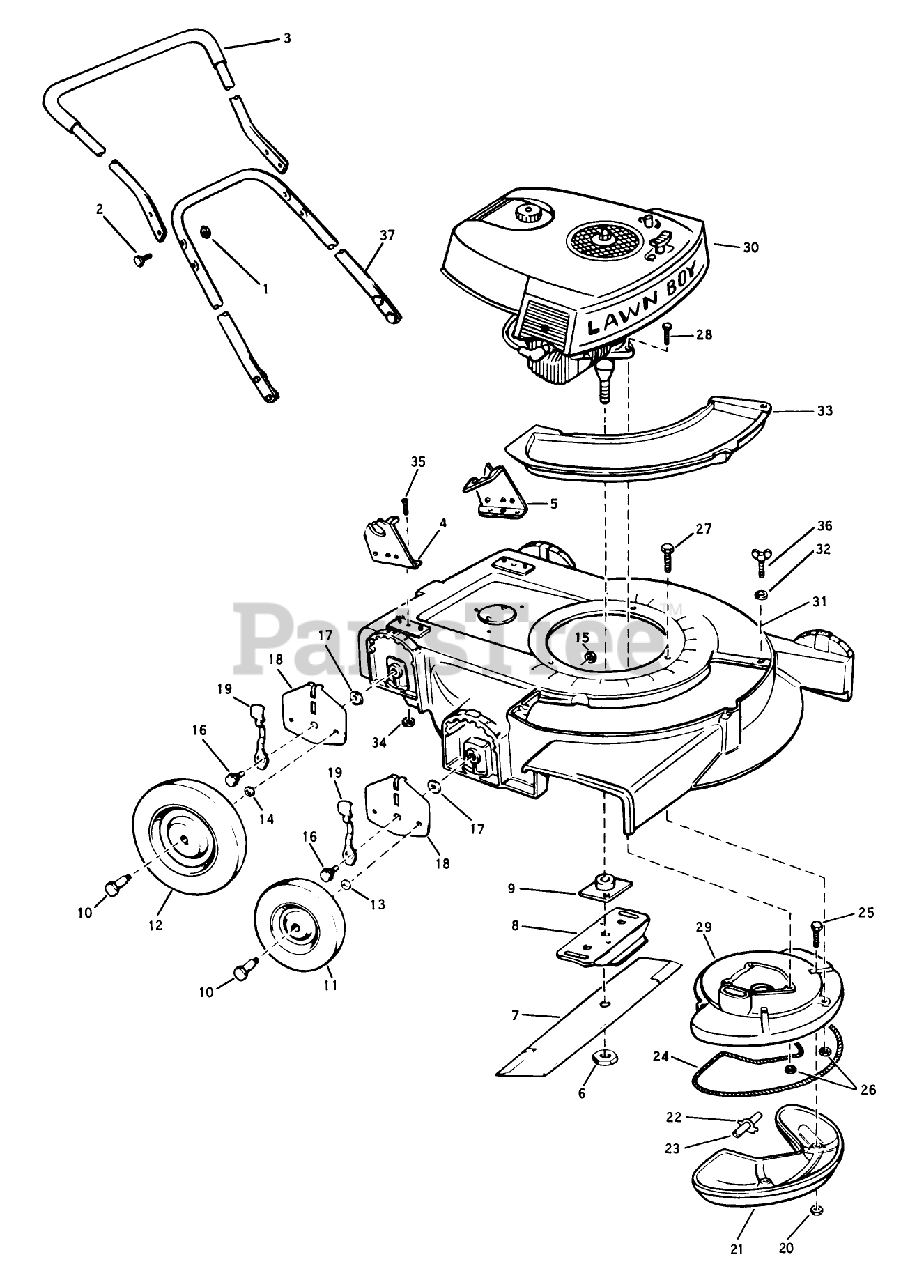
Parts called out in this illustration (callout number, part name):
1	STOP NUT
3	Handle Grip Assy. Top
6	NUT-BLADE
9	PLATE AND COLLAR ASM
10	BOLT WHEEL
13	WASHER WROUGHT
14	WASHER WROUGHT
20	LOCKNUT E
22	Gasket-Internal Tube
23	Tube-Internal Muffler
31	Housing Cover Assy. 19"
35	SCREW S
